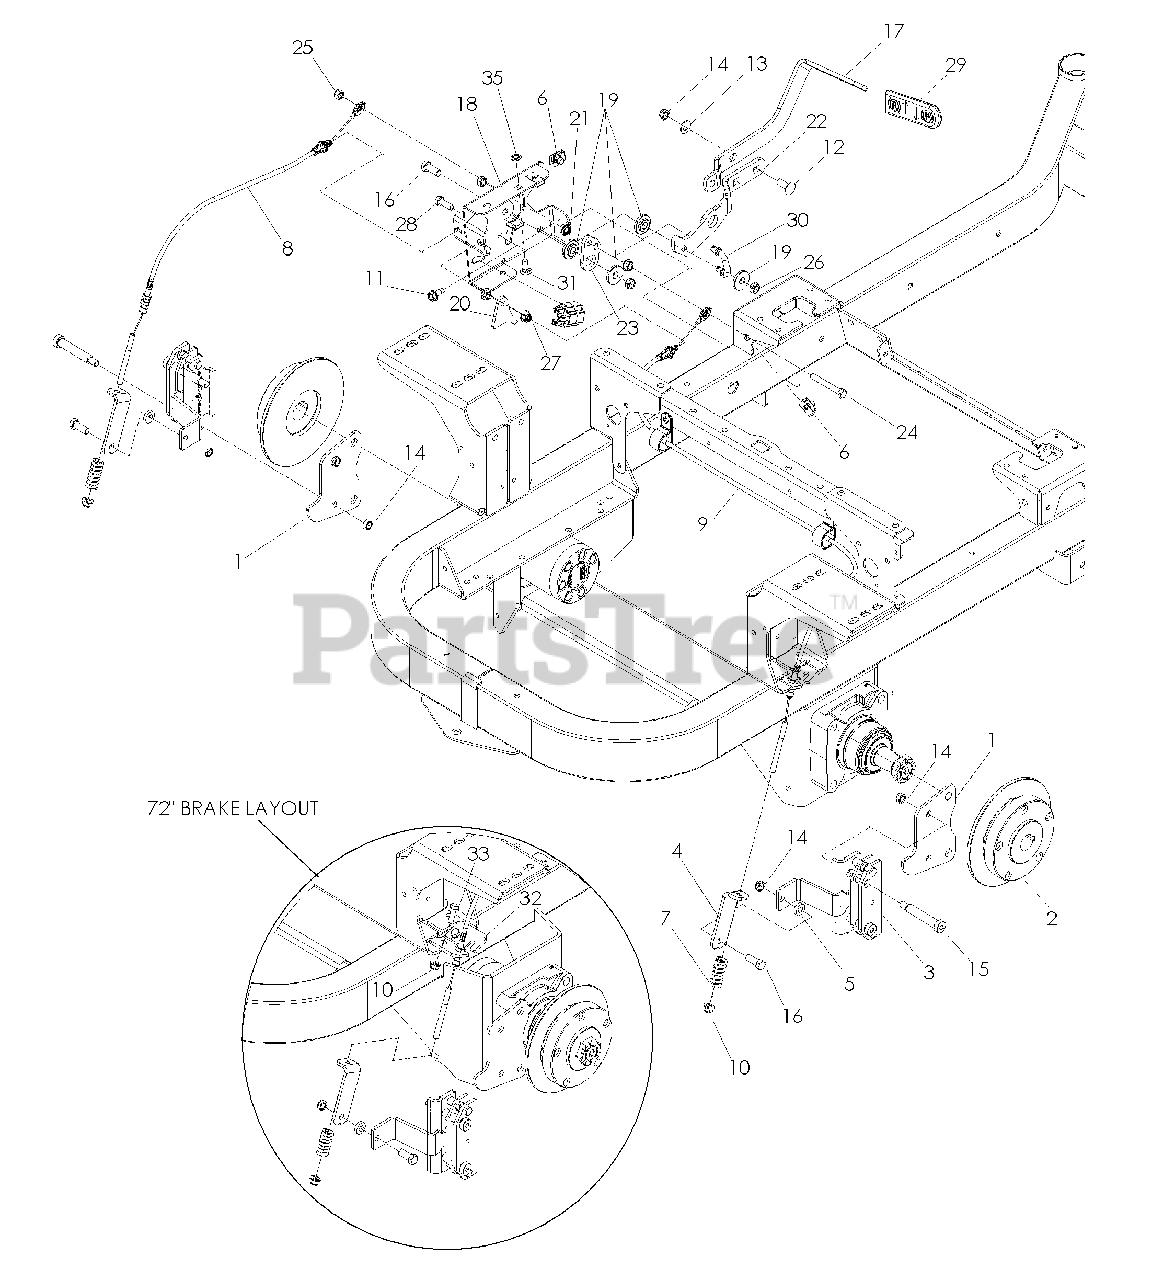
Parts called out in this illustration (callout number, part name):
1	PLATE, BRAKE
2	HUB, 5 BOLT
3	CALIPER, PARK BRAKE
4	BRACKET, L
5	WASHER 3/8 x 3/4 x .187 TK
6	RETAINER, U TYPE
8	CABLE, BRAKE, SHORT
9	CABLE, BRAKE, LONG
10	NUT 5/16-18 FLANGE NYLOC
11	BOLT 5/16-18 x 3/4 THD FRM
12	RHSNB 3/8-16 x 1
13	WASHER, 3/8 SAE FLT
14	NUT 3/8-16 HEX JAM NYLOC
15	SB 3/8-16 x 2 1/2 SKT HD
16	HCS 3/8-16 x 1ZD
17	ARM, BRAKE
18	MOUNT, BRAKE WELDMENT
19	BUSHING, BRAKE
20	ACTUATOR, SWITCH
21	NUT 5/16-18 HEX WHIZLK
22	LEVER, BRAKE
23	BELLCRAKE, BRAKE
24	HCS 5/16-18 x 2 1/2 TPBLT
25	NUT 5/16-18 HEX NYLOC
26	NUT 3/8-16 HEX JAM NYLOC
27	NUT 5/16-18 FLANGE NYLOC
28	HCS 5/16-18 x 1ZD
29	GRIP, BRAKE HANDLE
30	LINKAGE, BRAKE
31	RHSNB 5/16-18 x 3/4 GR5
32	BRKT, EXTENSION 72" ONLY
33	HCS 5/16-18 x 1
